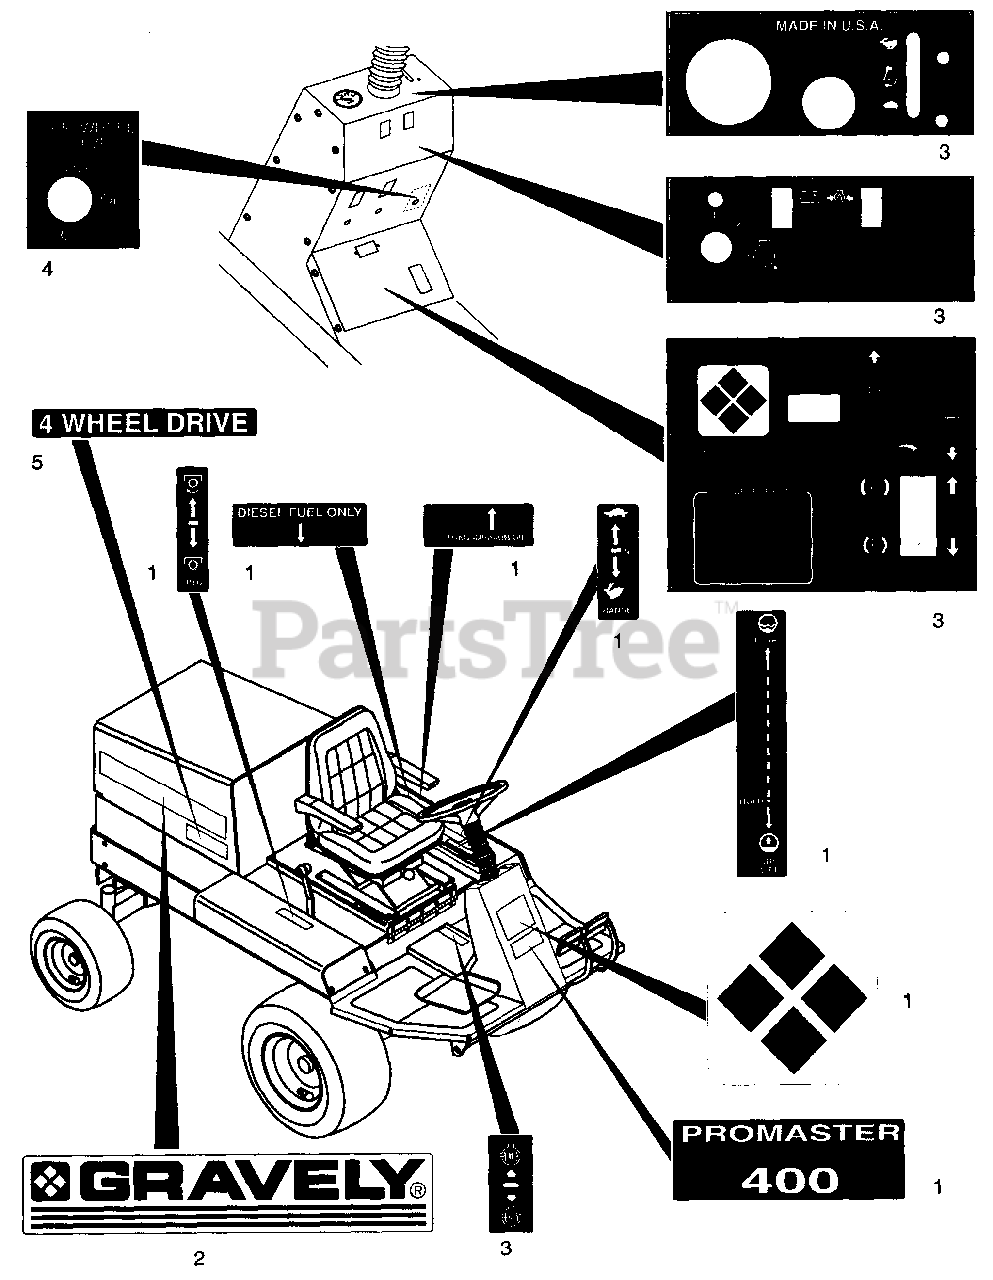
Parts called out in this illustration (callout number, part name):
1	Decal Set
2	Gravely Name/Logo/Stripe Decal
3	Decal Set
4	Four Wheel Drive Decal
5	Decal, Four Wheel Drive
